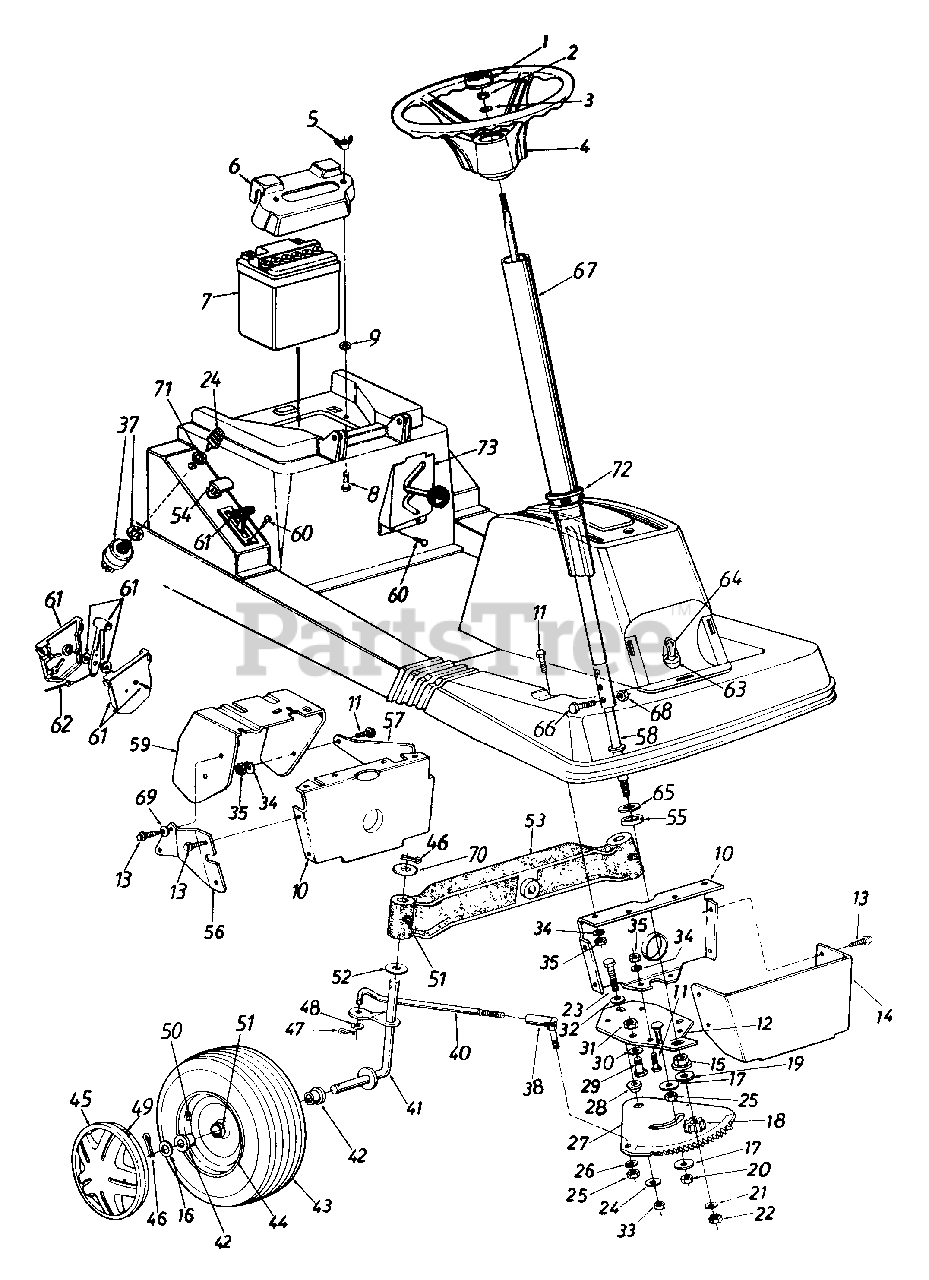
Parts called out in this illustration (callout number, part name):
1	Steering Wheel Cap
2	Hex L-Nut 5/16-24 Thd.
3	Bell-Wash. .345" I.D. x .88" O.D.
4	Steering Wheel Ass'y.
5	Wing Nut 1/4-20 Thd. (Nylon)
6	Battery Hold Down Cover
7	12V Battery
8	Hex Bolt 1/4-20 x 1.75" Lg.
9	Push On Retaining Ring
12	Steering Gear Support Brkt. Ass'y.
13	Hex Wash. Hd. AB-Tap Scr. 1/4 x .62" Lg.
16	FI-Wash. .635" I.D. x 1.585"
17	FI-Wash. .385" x 1.37" O.D.
18	Steering Pinion Gear
19	FI-Wash. .510" I.D. x 1.0" O.D.
20	Hex L-Nut 3/8-24 Thd.
21	FI-Wash. .34" I.D. x .68" O.D.
22	Hex Nut 5/16-24 Thd.
23	Hex Bolt 3/8-24 x 1.5" Lg. (Gr. 5)
24	Ignition Key Set
25	Hex Nut 3/8-24 Thd.
26	L-Wash. 3/8" I.D.
27	Steering Gear Segment
28	Shld. Spacer
29	Hex Bolt (Nylon) 1/2-13 x .75" Lg.
30	FI-Wash. .53" I.D. x .93" O.D.
31	Hex Nut 1/2-13 Thd.
32	Bell-Wash. .385" I.D. x .88"
34	L-Wash. 5/16" I.D.
35	Hex Nut 5/16-18 Thd.
37	Ignition Switch
38	Ball Joint Ass'y.
40	Steering Tie Rod
41	Front Axle Ass'y - R.H.
42	Wheel Bearing
46	Cotter Pin 1/8" Dia. x 1.25" Lg
47	Cotter Pin 1/8" Dia. x 1.0" Lg.
48	FI-Wash. .385" I.D. x 87" O.D.
49	Spring Clip
50	Air Valve
51	Grease Fitting
52	Fl-Wash .76" I.D. x 1.49" O.D.
55	Spacer .985" I.D. x 1.25"
61	Throttle Control Box Ass'y
62	Throttle Control Wire 22" Lg
63	Headlight Socket
64	Lamp
65	Fl-Wash. 64" I.D. x 1.24"
66	Hex Bolt 1/4-20 x 1.25" Lg.
67	Steering Shaft Ass'y.
68	Hex L-Nut 1/4-20 Thd
69	Bell-Wash. .345" I.D. x .88" O.D.
70	Fl-Wash. .75" I.D. x 1.5" O.D.
71	Ignition Switch Nut
72	Steering Cover Brg.
73	FNR Index Brkt
